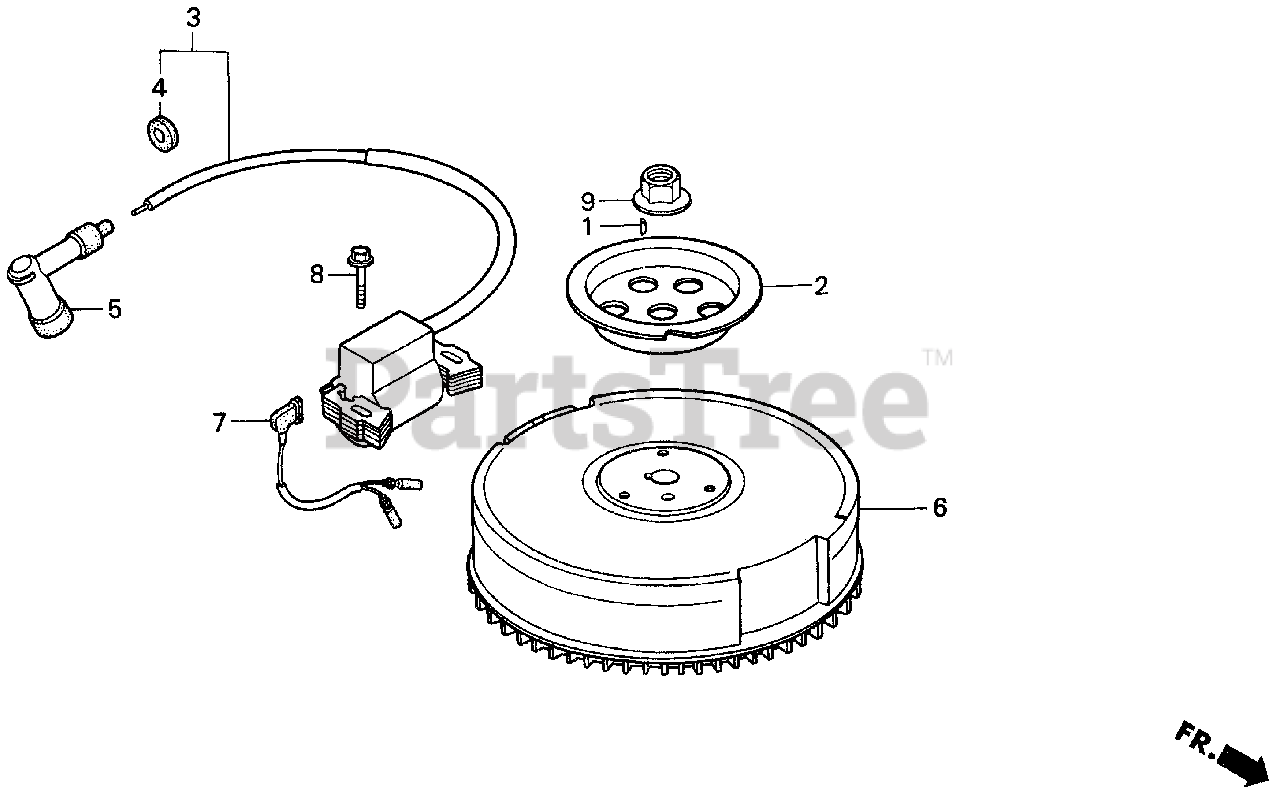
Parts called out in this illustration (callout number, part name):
1	KEY, SPECIAL WOODRUFF (25X18)
2	PULLEY, STARTER
3	COIL ASSY., IGNITION
4	GROMMET, IGNITION WIRE
5	CAP ASSY., NOISE SUPPRESSOR
6	FLYWHEEL
7	WIRE, STOP SWITCH
8	BOLT, FLANGE (6X25)
9	NUT, SPECIAL (14MM)
